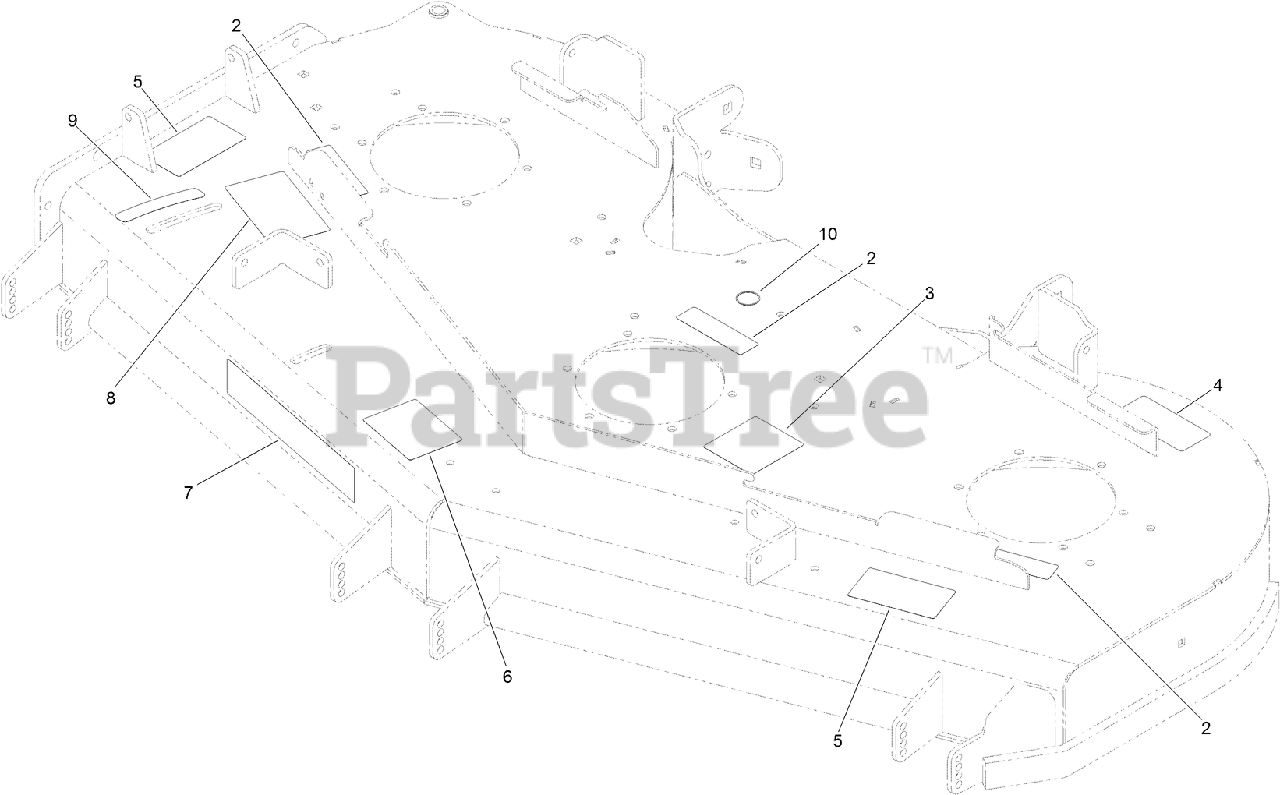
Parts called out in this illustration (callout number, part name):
2	DECAL-MISSING, COVER
3	DECAL-ROUTING, DECK BELT
4	DECAL-TORQUE, BLADE BOLT
5	DECAL-DANGER
6	DECAL-ANTI SCALP
8	DECAL-ADJUSTMENT, BAFFLE
9	DECAL-SETTING, BAFFLE
10	DECAL-GREASE
